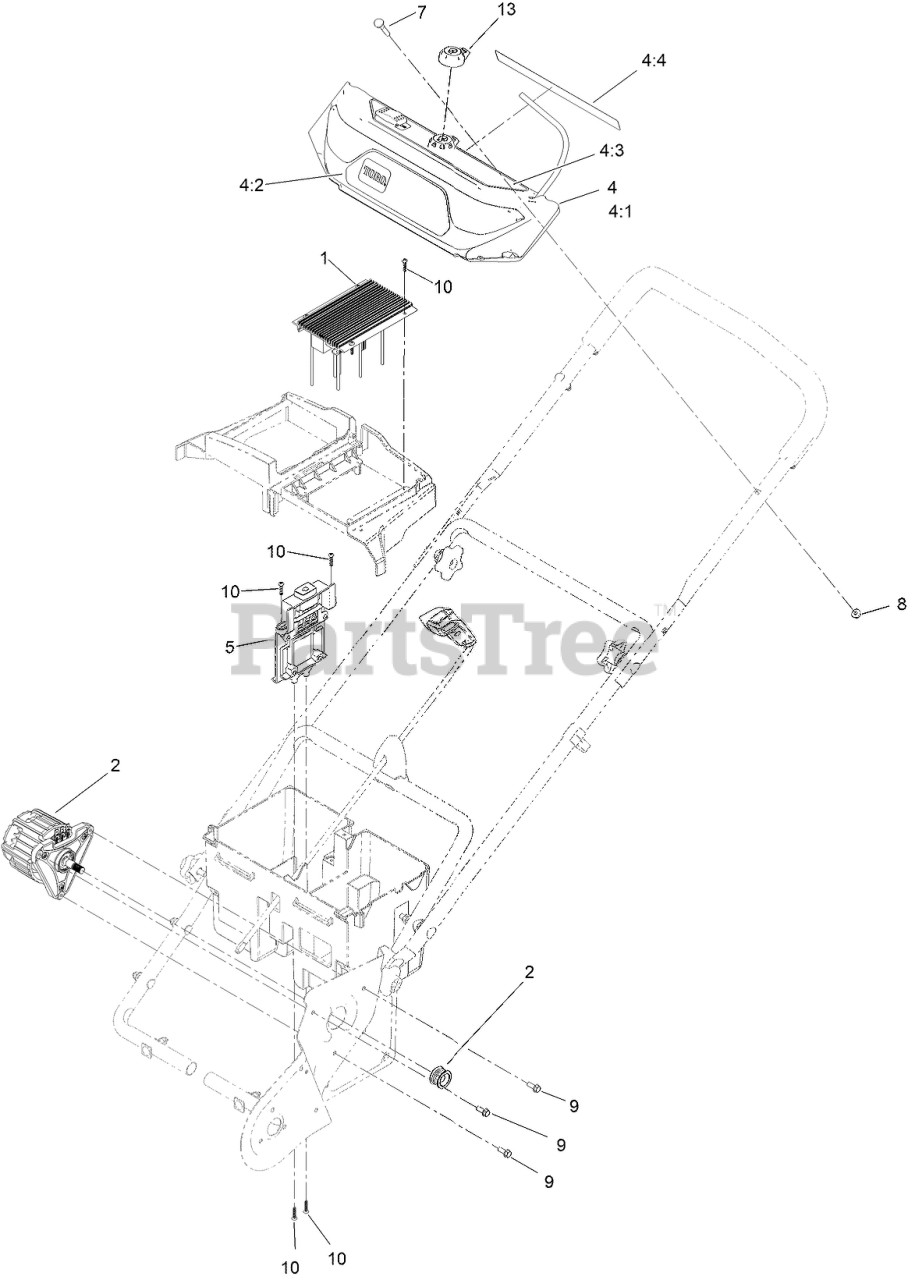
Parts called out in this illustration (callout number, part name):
1	MOTOR-DRIVER, SNOW (60V)
2	MOTOR-60V
4	DASH PANEL ASM W/DECALS
4:1	DASH PANEL ASM
4:2	DECAL-POWER CLEAR
4:3	DECAL-OPERATION
4:4	DECAL-CAUTION
5	BATTERY TRACK ASSEMBLY
7	SCREW-HANDLE
8	NUT-FLANGE, NI
9	SCREW-HWH
10	SCREW-PPH
13	KEY-BAIL
